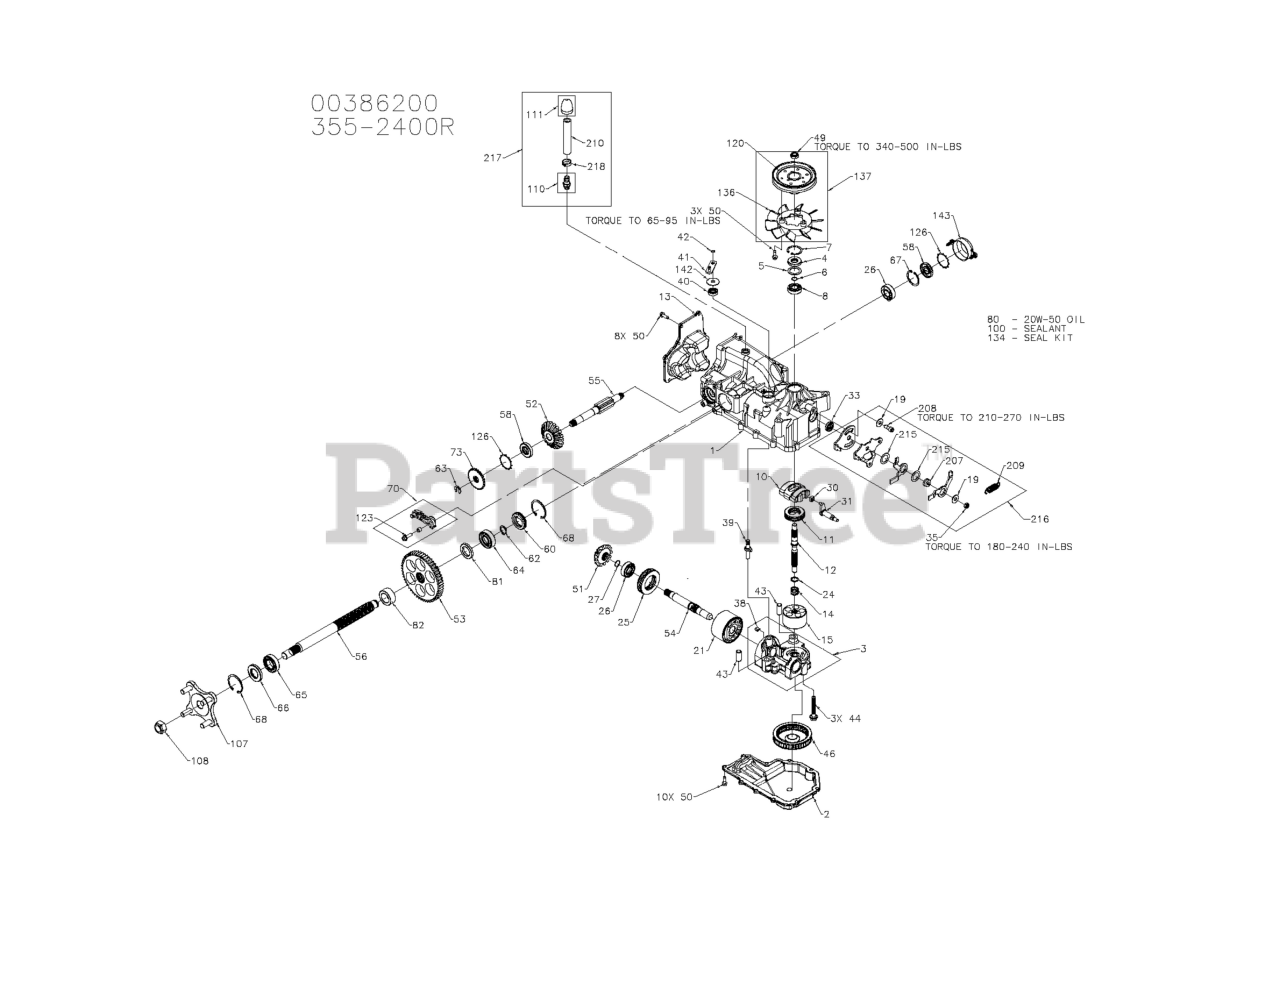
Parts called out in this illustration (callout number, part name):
1	KIT, MAIN HOUSING
2	Lower Housing
3	KIT, C-SECTION
4	SEAL, LIP 15X35X7
5	WASHER .98X1.37X.04
6	RING, WIRE RETAINING
7	RING. RETAINING
8	BEARING, SHAFT BALL
10	SWASHPLATE. VARIABLE
11	BEARING. THRUST 30 X 52 X 13
12	SHAFT, INPUT
13	COVER, END IZT
14	SPRING. BLOCK
15	KIT, 10 CC BLOCK
21	ASSEMBLY BLOCK
24	WASHER. THRUST .59 X .79 X .04
25	BRG, THRUST BALL 42X68X16
26	BRG, BALL 17X40X12
27	RING, RET WIRE .561 ID
30	GUIDE. SLOT
31	ARM. TRUNNION TAPERED SQUARE
33	SEAL, LIP 12X25X7
35	NUT, LOCK, 5/16-24 UNF
38	KIT, BYPASS PLATE
39	ACTUATOR, BYPASS
40	SEAL, LIP
41	ARM. BYPASS
42	RING, RETAINING
43	PIN-HOLLOW .39X.5X1.
44	HFHCS 3/8-24X2.5 (PATCH)
49	HEX LOCK NUT, 1/2-20 (NYLON INSERT)
50	HFHCS 1/4-20X.75
51	GEAR, BEVEL 14T
52	GEAR, BEVEL 19T
53	GEAR, SPUR 53T
54	SHAFT, MOTOR
55	SHAFT, BRAKE
56	AXLE, 1.0X12.3
58	SEAL, LIP 17X40X7
60	PLUG, SEAL 1.86
62	RING, RET .75 EXT
63	RING, RET .440 EXT
64	BRG, BALL 20X47X14
65	BRG, BALL 25X47X12
66	SEAL, LIP 25X47X7
67	RING, RET 1.56 INT
68	RING, RET 1.87 INT
70	BRAKE ARM,RH IZT
73	BRAKE, PARK SPLINE
80	FLUID, HYDRO 15W50 QT
80	FLUID, HYDRO 20W50 QT
100	SEALANT TUBE 10.1OZ.
107	ASSEMBLY, HUB
110	FTG-STR .50 O-RING
111	BREATHER ASSEMBLY
120	PULLEY, 4.5 IN
123	SCREW, HFH 1/4-28 X 7/8 PATCH
126	RING, RET 1.43"
134	KIT, SEAL
136	FAN-6IN
137	KIT, FAN/PULLEY
142	WASHER, .392 X 1.250 X .0
143	CAP, BRAKE
208	SHCS 5/16-24X.75
209	SPRING, EXTENSION
210	HOSE .5X4
215	ASSEMBLY, RTN
216	KIT, RTN
217	KIT, BREATHER
